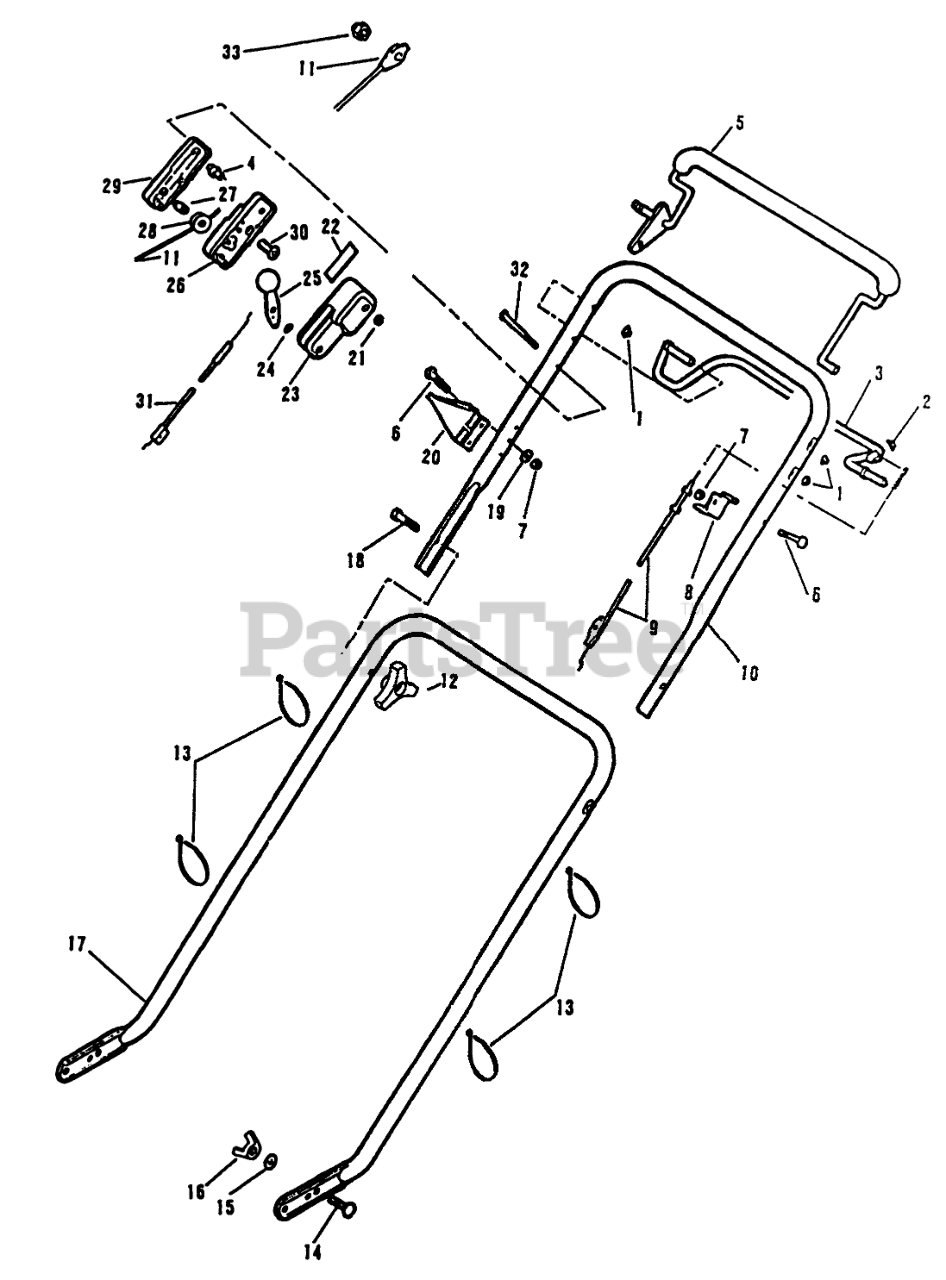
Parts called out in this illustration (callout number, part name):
1	NUT-PUSH
2	NUT
3	CONTROL LEVER AY.
4	COLUMN
5	CONTROL LEVER ARG
6	SCREW
7	LOCKNUT E
8	ANCHOR C'DUIT TRO
9	CABLE - CONTROL
10	Handle-Top
11	CONTROL CABLE
12	Knob
13	TIE-CABLE
14	Bolt
15	WASHER LOCK B'GER
16	NUT WING
17	HDLE-LOWER(GREEN
18	Screw
19	WASHER
20	GUIDE - ROPE
21	NUT C/LOCK E
22	DECAL-THROT CONTRL
23	INNER CONTROL CASE
24	WASHER-SPRING
25	LEVER&KNOB AY WES
26	CENTER CONTROL CASE
27	PIN SKF
28	PULLEY PL
29	OUTER CONTROL CASE
30	SCREW
31	CABLE TH'TTLE WES
32	SCREW
33	NUT ACORN
